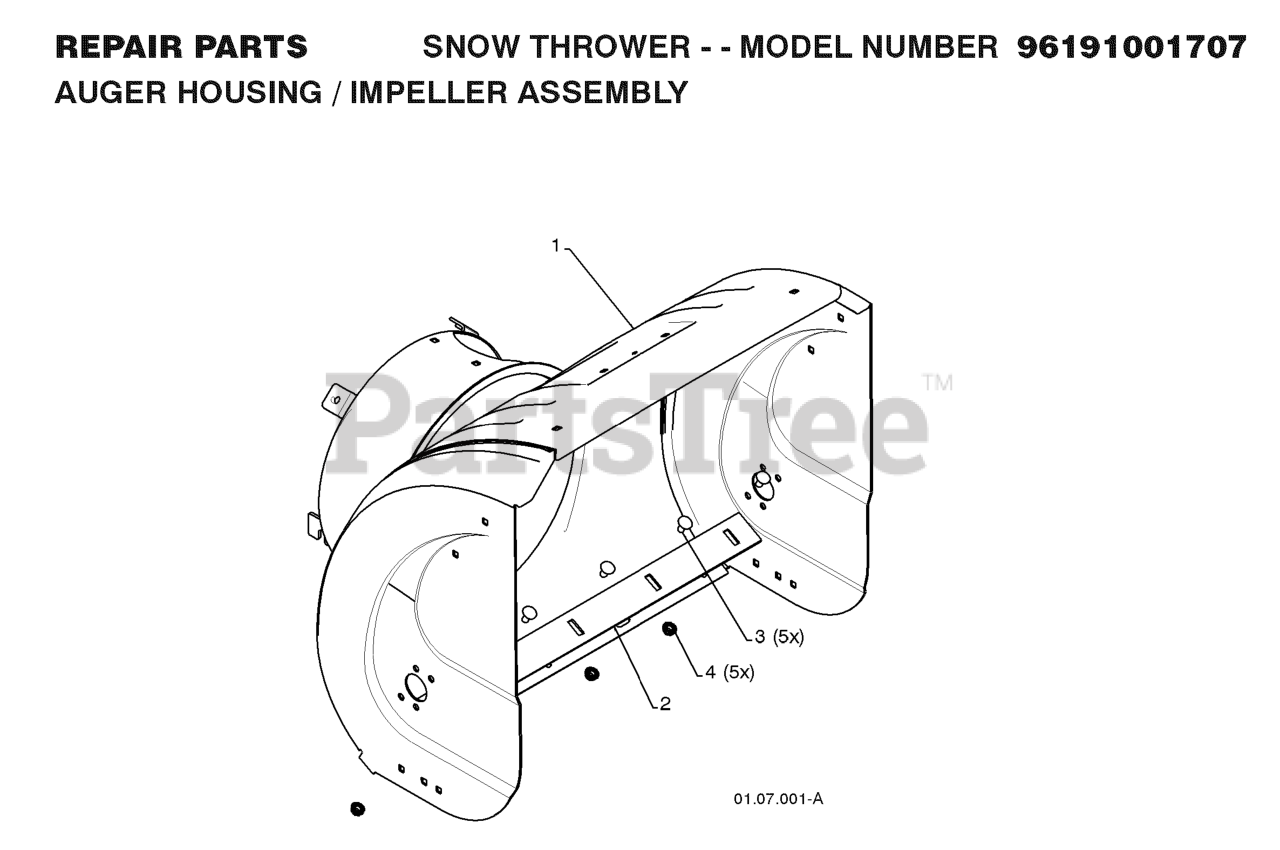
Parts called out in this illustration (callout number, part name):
1	AUGER HOUSING
2	BAR, SCRAPER
3	BOLT
4	NUT.FLANGE.5/16
